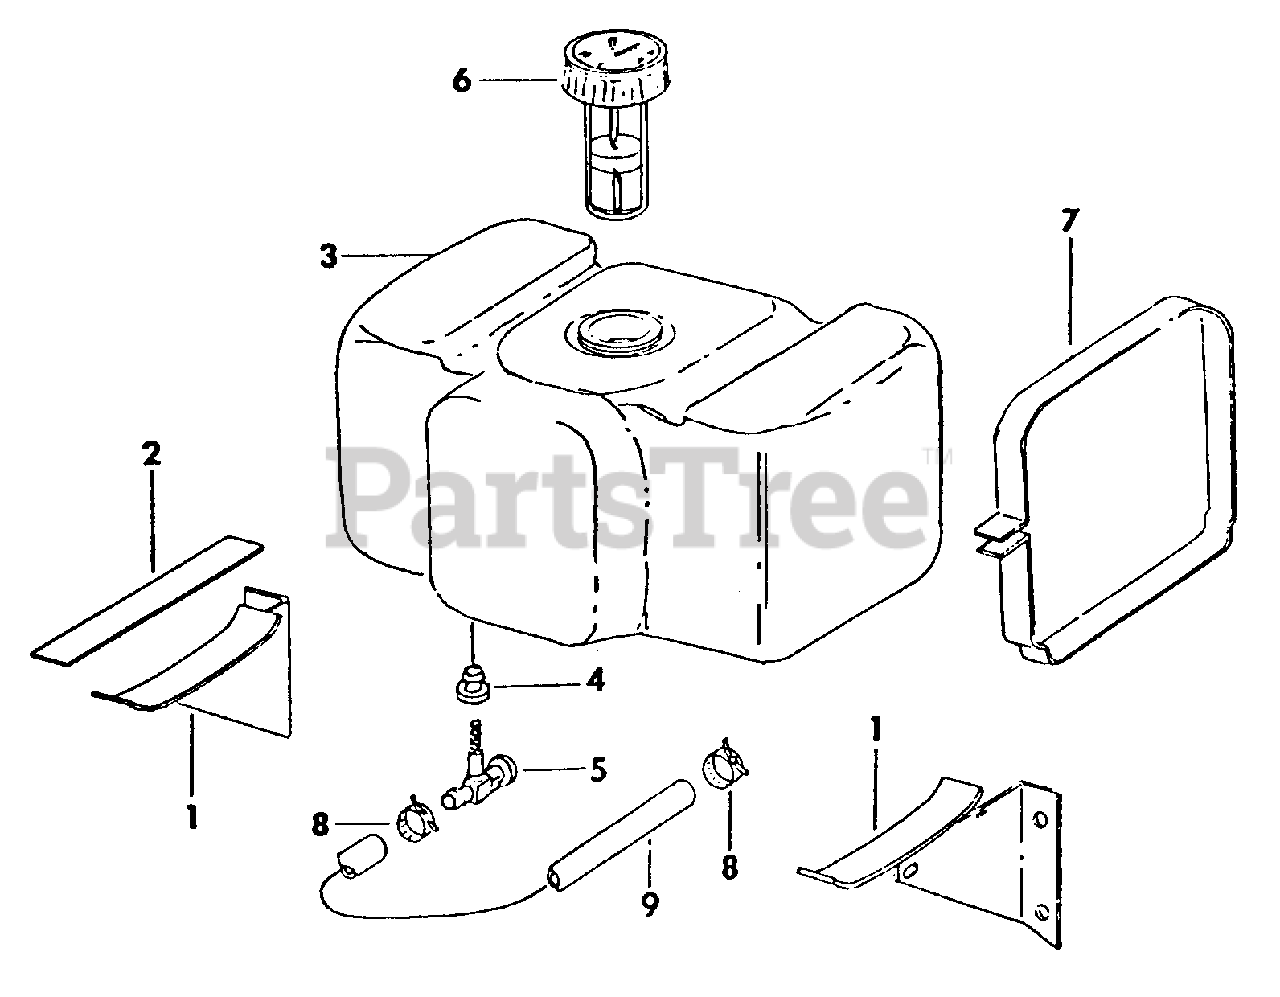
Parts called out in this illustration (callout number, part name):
1	Bracket Assy, Tank LH
2	Pad, Fuel Tank
3	Tank, Fuel
4	Bushing, Shut-Off
5	Shut-Off Assy, Valve
6	Cap, Fuel Tank
7	Strap, Fuel Tank
8	Clamp, Hose
9	Hose
